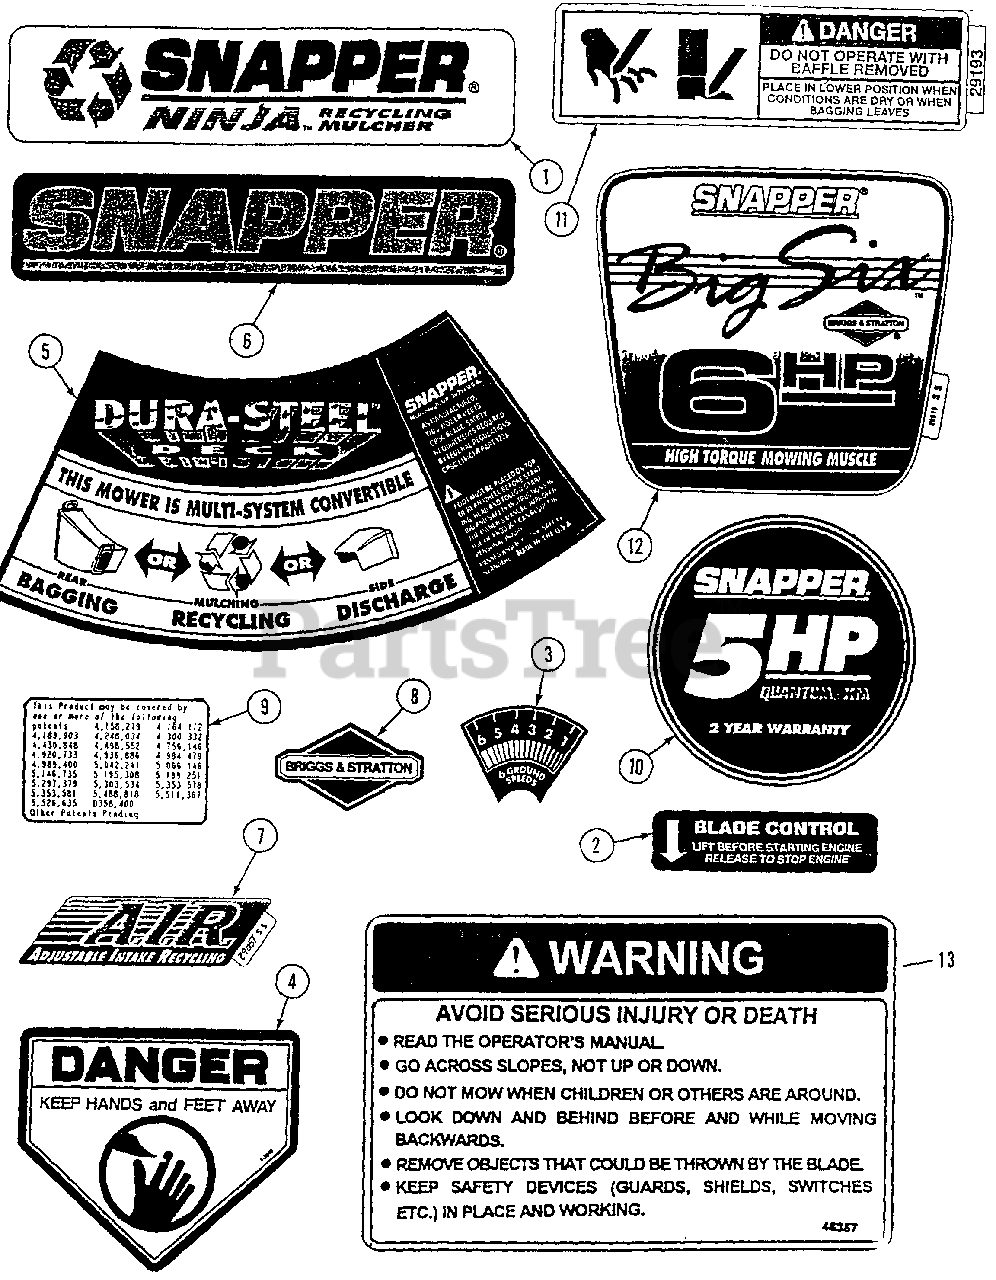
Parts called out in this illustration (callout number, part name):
1	LOGO, Recycling Mulcher (Ninja)
2	DECAL, Blade Control
3	DECAL, Speed Sector
4	DECAL, Danger
5	DECAL, Dura-Steel Convertible/Compliance
6	DECAL, Snapper
7	DECAL, Medallion - Deck
8	DECAL, Briggs & Stratton
9	DECAL, Patent Numbers
10	DECAL, Snapper 3.87 Diameter
11	DECAL, Baffle Front
12	DECAL, 6HP
13	DECAL, Warning
